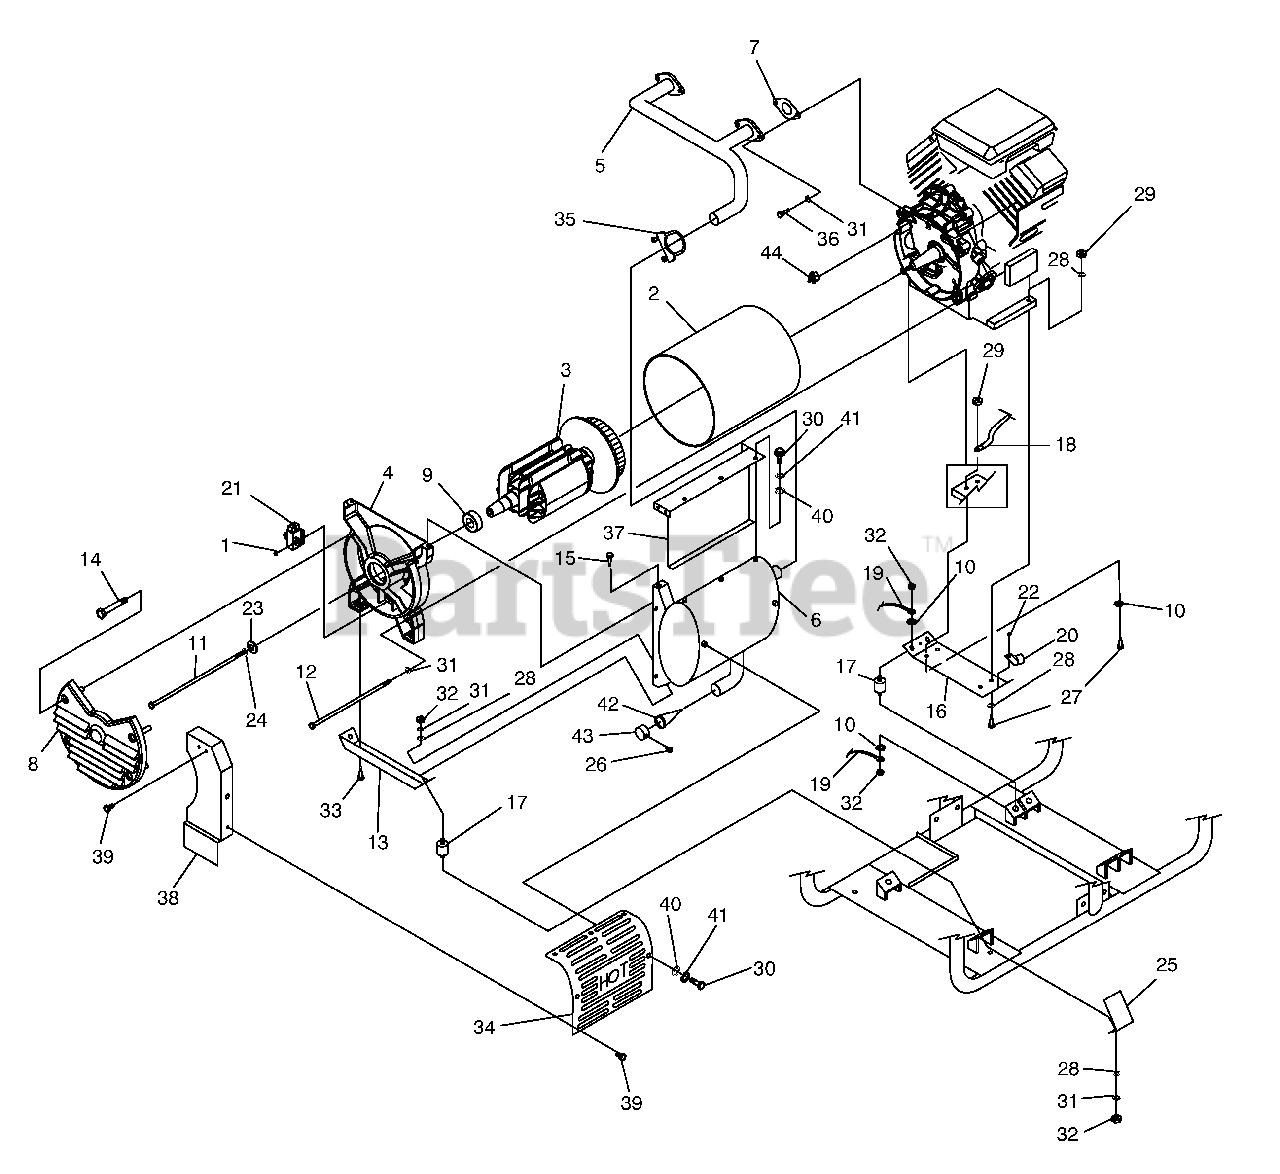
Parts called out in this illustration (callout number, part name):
1	SCREW HHTT M5-0.8 X 16
2	STATOR 15KW
3	ASSEMBLY, ROTOR WITH FAN 15KW
4	CARRIER, REAR BEARING
5	EXHAUST MANIFOLD
6	MUFFLER
7	GASKET, EXHAUST
8	COVER, ALTERNATOR AIR IN
9	BEARING
10	5/16 SPECIAL LOCK WASHER
11	SCREW IHHC 3/8-24 X 15.50 G5
12	SCREW IHHC M8-1.25 X 400 G8.8
13	BRACKET, ALT MOUNTING
14	SCREW HHTT #10-32 X 1.75
15	SCREW HHTT M8-1.2 X 20
16	ENGINE MOUNTING PLATE
17	RUBBER MOUNT
18	BATTERY CABLE, BLACK
19	EARTH STRAP 3/8X 3/8
20	CLIP-J VINYL COAT .625 ID
21	ASSEMBLY, BRUSH HOLDER
22	SCREW TAP-R #10-32 X 9/16
23	WASHER FLAT 3/8 ZINC
24	WASHER LOCK 3/8
25	SHIELD, RUBBER MOUNT
26	SCREW HHTT M4-0.7 X 8
27	SCREW HHC M8-1.25 X 50 G8.8
28	WASHER FLAT 5/16 ZINC
29	NUT LOCK HEX M8-1.25 NYLON INSERT
30	SCREW HHC M6-1.0 X 12
31	WASHER LOCK M8-5/16
32	NUT HEX 5/16-18 STEEL
33	SCREW TAPTITE 3/8-16 X 3/4 BP
34	SHIELD, MUFFLER HEAT
35	U-BOLT & SADDLE
36	SCREW SHC M8-1.25 X 18
37	PANEL, MUFFLER BOX BACK
38	PANEL, MUFFLER BOX END
39	SCREW HHTT M6-1.0 X 12
40	WASHER FLAT M6-1/4
41	WASHER LOCK M6-1/4
42	SPARK ARRESTOR SCREEN
43	RETAINER, SPARK ARREST SCREEN
44	PLUG, GEARCOVER ADAPTOR
